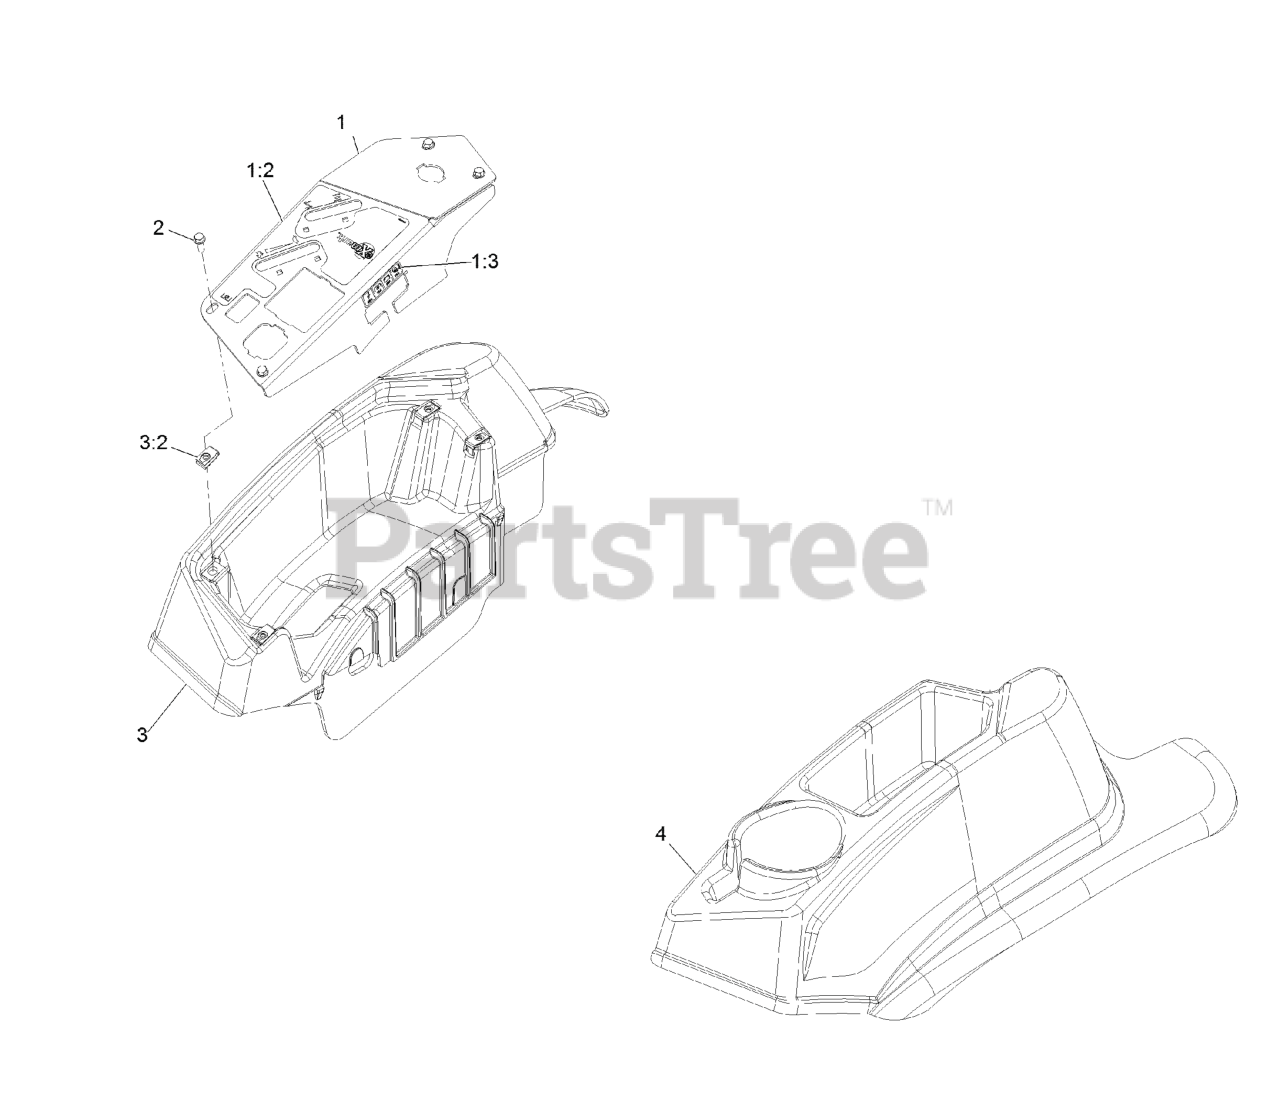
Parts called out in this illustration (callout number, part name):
1	ASM-PANEL, CONTROL W/DECAL
1:2	DECAL-CONTROL PANEL NON-EFI
1:3	DECAL-FUSES
2	SCREW-HWH
3	CONSOLE,RH AS ASM
4	CONSOLE, LH AS
